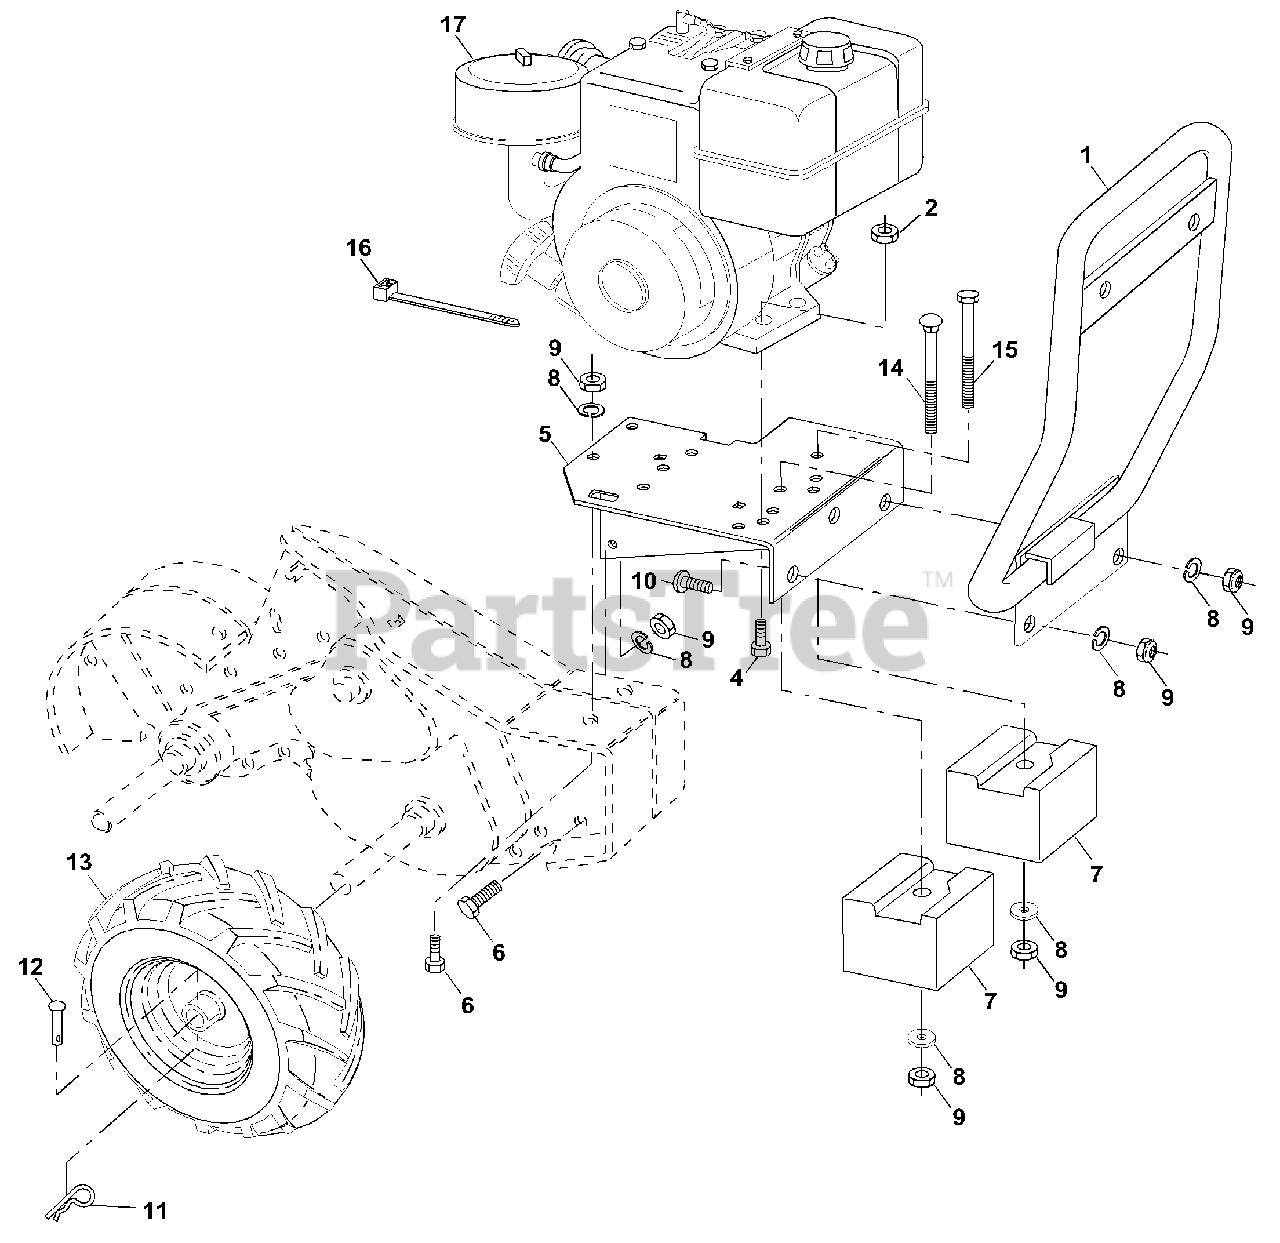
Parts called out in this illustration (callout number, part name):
2	Nut, Keps 5/16-18
4	Bolt, Hex 5/16-18 x 1-3/4
5	Bracket, Engine
6	Bolt, Hex Head 3/8-16 x 1
7	Counter Weight, R.H.
8	Washer, Lock 3/8
9	Nut, Hex 3/8-16
10	Bolt, Carriage 3/8-16 x 1
11	Clip, Hairpin
12	Rivet, Drilled
13	Rim
13	Tire Valve
14	Bolt, Carriage 3/8-16 x 4-1/2
15	Bolt, Hex Head 3/8-16 x 4-1/2
16	Tie, Cable
